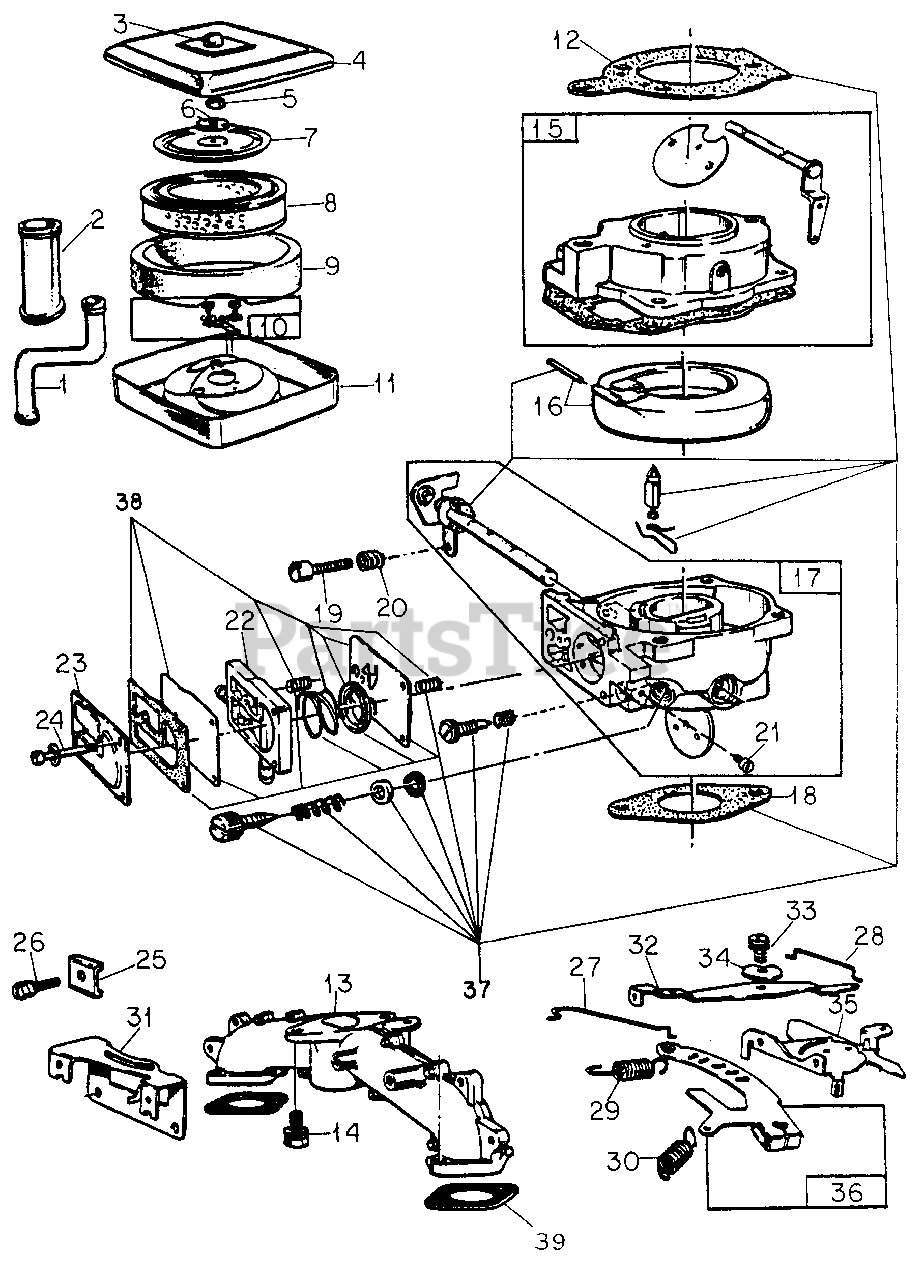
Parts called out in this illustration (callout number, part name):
1	Tube, Breather
2	Tube, Breather
3	Knob, Air Cleaner
4	Cover, Air Cleaner
5	Nut, Air Cleaner
6	Washer, Retainer
7	Plate, Retainer
8	Cartridge, Air Cleaner
9	Element, Air Cleaner
10	Strap Assy, Air Cleaner Mounting
11	Body, Air Cleaner
12	Gasket, Air Cleaner
13	Manifold, Intake
14	Screw, Carburetor Mtg
15	Body Assy, Carburetor Upper
16	Float Assy, Carburetor
17	Body Assy, Carburetor Lower
18	Gasket, Carburetor
19	Screw, Throttle Adj
20	Spring, Throttle Adj
21	Screw, Clamp Set
22	Body, Pump
23	Cover, Pump Body
24	Screw, Cover Mtg
25	Clamp, Casing
26	Screw, Clamp
27	Link, Governor
28	Link, Speed Control
29	Spring, Governor
30	Spring, Governor Idle
31	Bracket, Speed Control
32	Lever, Speed Control
33	Screw, Speed Control Lever
34	Washer, Speed Control
35	Plate Assy, Governor Control
36	Lever Assy, Governor
37	Kit, Carburetor Overhaul
38	Kit, Fuel Pump Repair
39	Gasket, Manifold
